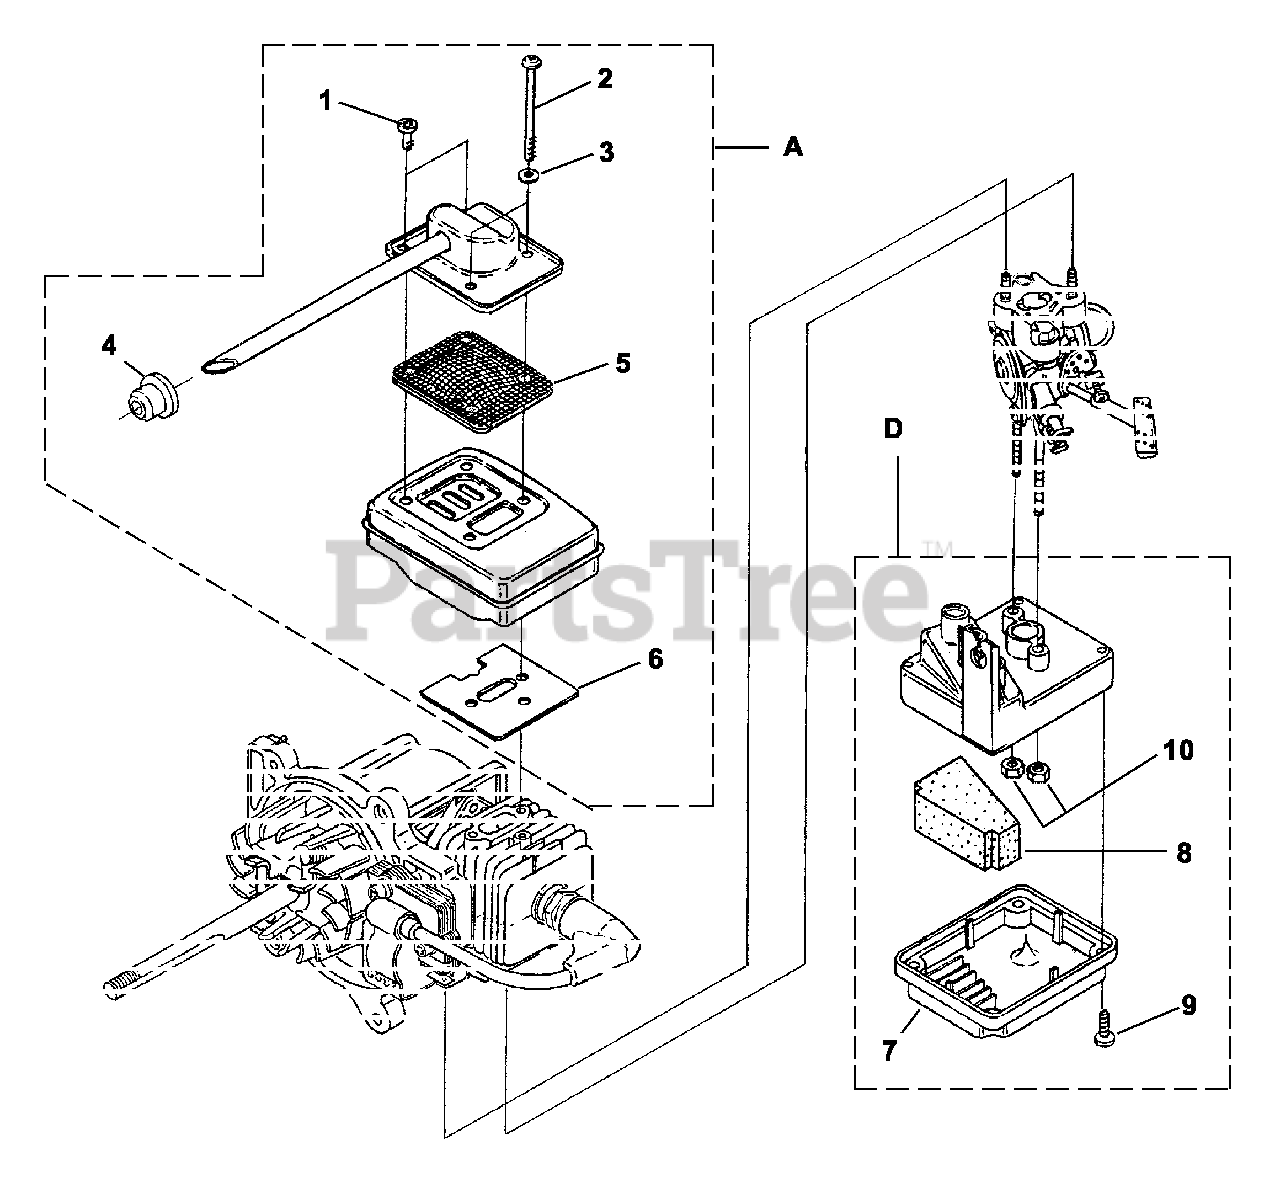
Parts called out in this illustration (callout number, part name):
1	Screw, Taptite (8-32 x 3/8)
2	Screw, Torx Truss Hd. (10-24 X 2.188")
3	Washer, Conical #10
4	Muffler Grommet
5	Screen Assy., Spark
6	Gasket, Muffler
7	Cover, Air Box
8	Filter Element #1
9	Screw, Thread Forming (8-16 X .50)
10	Nut, Lock Hex (10-24)
A	Muffler Assembly, Crimped
D	Air Filter Assembly
